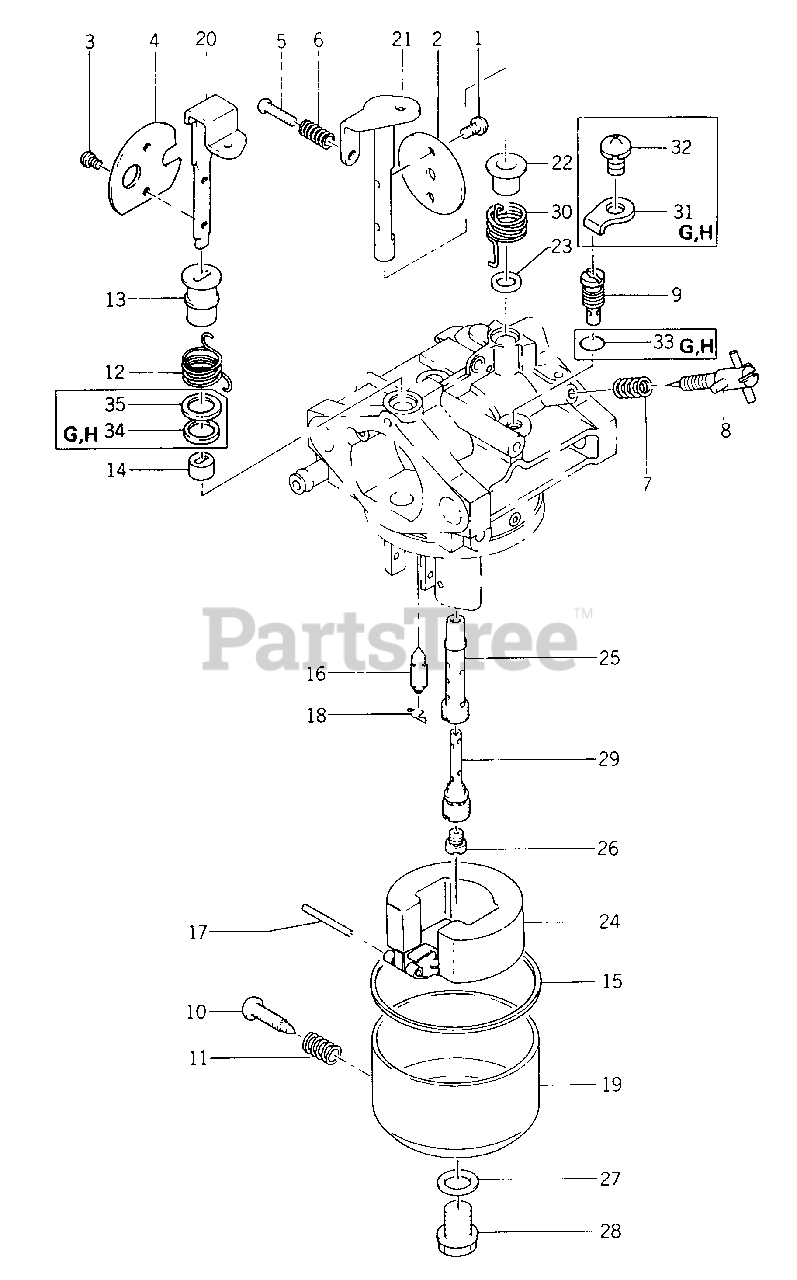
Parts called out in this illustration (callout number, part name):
1	SCREW
2	VALVE, throttle (#100)
3	SCREW
4	VALVE, choke
6	SPRING
7	SPRING
8	SCREW, adjuster
9	JET, pilot (#47.5)
10	SCREW, drain
11	SPRING
14	RING
15	GASKET
16	VALVE, needle
17	PIN, float
18	CLIP
19	CHAMBER, float
20	SHAFT, choke
21	SHAFT, throttle
23	SEAL
24	FLOAT
25	NOZZLE, main (#6A)
26	JET, main (#112.5)
27	WASHER
28	BOLT
29	PIPE, bleed
31	PLATE
32	SCREW
33	O-RING
34	SEAL
35	WASHER
